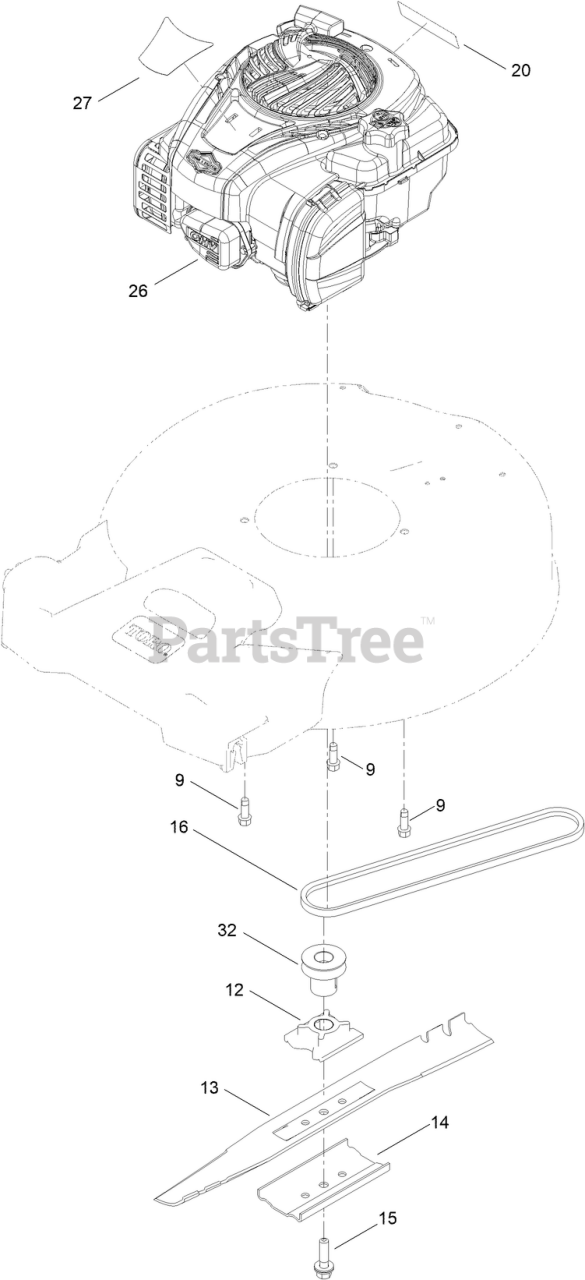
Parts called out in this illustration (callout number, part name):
9	SCREW-TAPTITE
12	RETAINER-BLADE
13	BLADE-21IN
14	SUPPORT-BLADE
15	BOLT-BLADE
16	BELT-V
20	DECAL-ARRESTOR, SPARK
26	ENGINE-BRIGGS, 550 EX
27	DECAL-ENGINE
32	PULLEY
